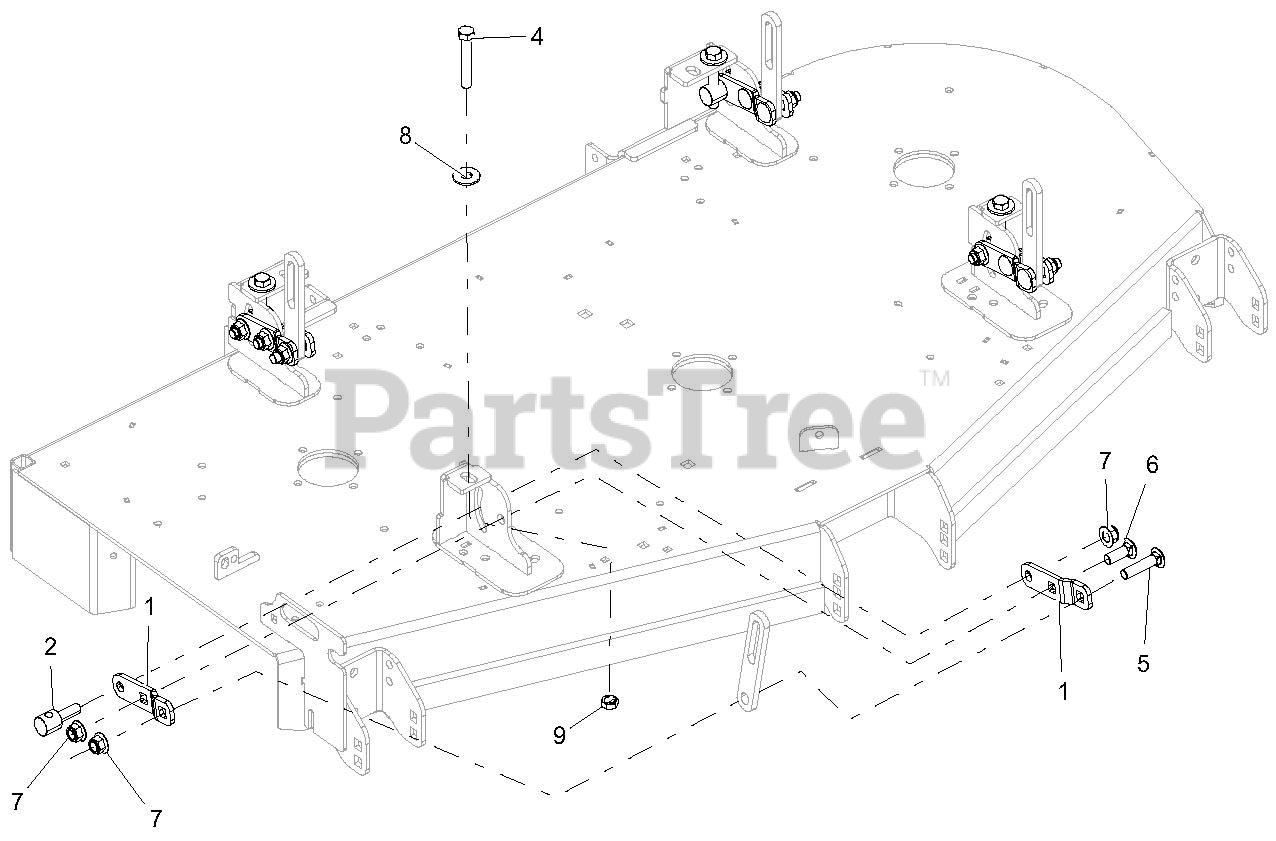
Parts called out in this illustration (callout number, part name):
1	BRKT, DECK LEVELING-BLACK
2	TRUNNION, .50-13
4	BLT-HEX .50-13X3.00 GR5 FTH YWZC
5	BLT-RDHDSQNK .50-13X2.25 G5Y
6	BLT-RDHDSQNK .50-13X1.50 G5 YWZC
7	NUT-LK-NYL-FLG .50-13 YWZC
8	WSHR-FL-STL.563X1.38X.109YWZC
9	NUT, JAM .500-13 YWZC
